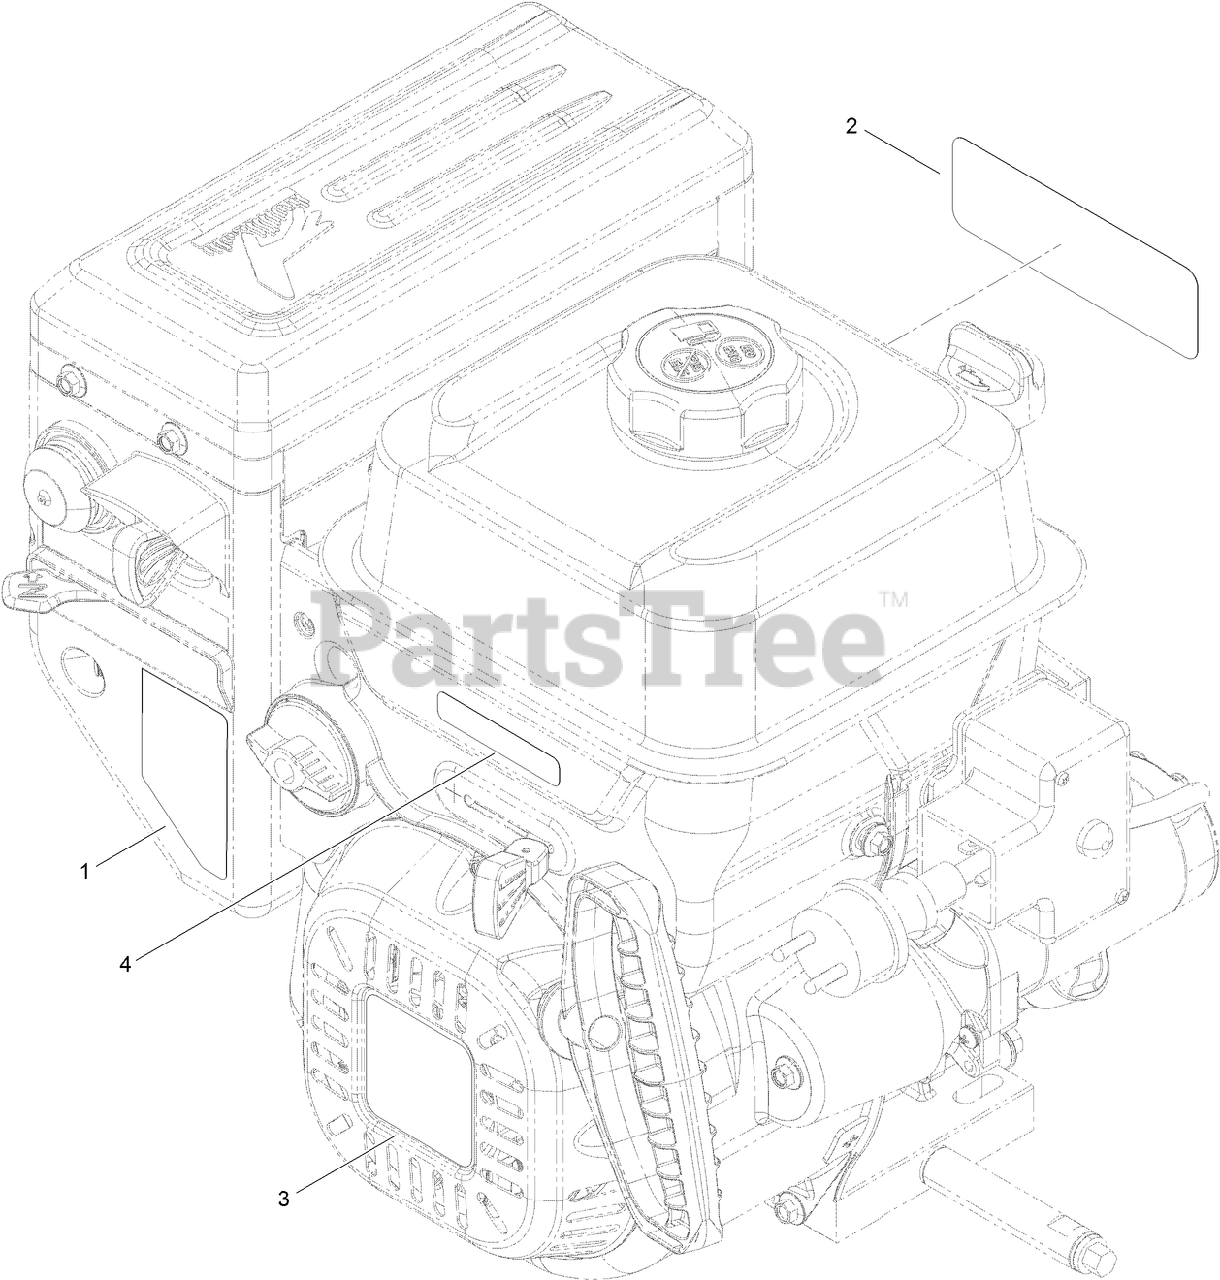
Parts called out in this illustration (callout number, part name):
1	DECAL-CONTROL, ENGINE
2	DECAL-ENGINE SERIES, G250
3	DECAL-RECOIL, G250
4	DECAL-THROTTLE
